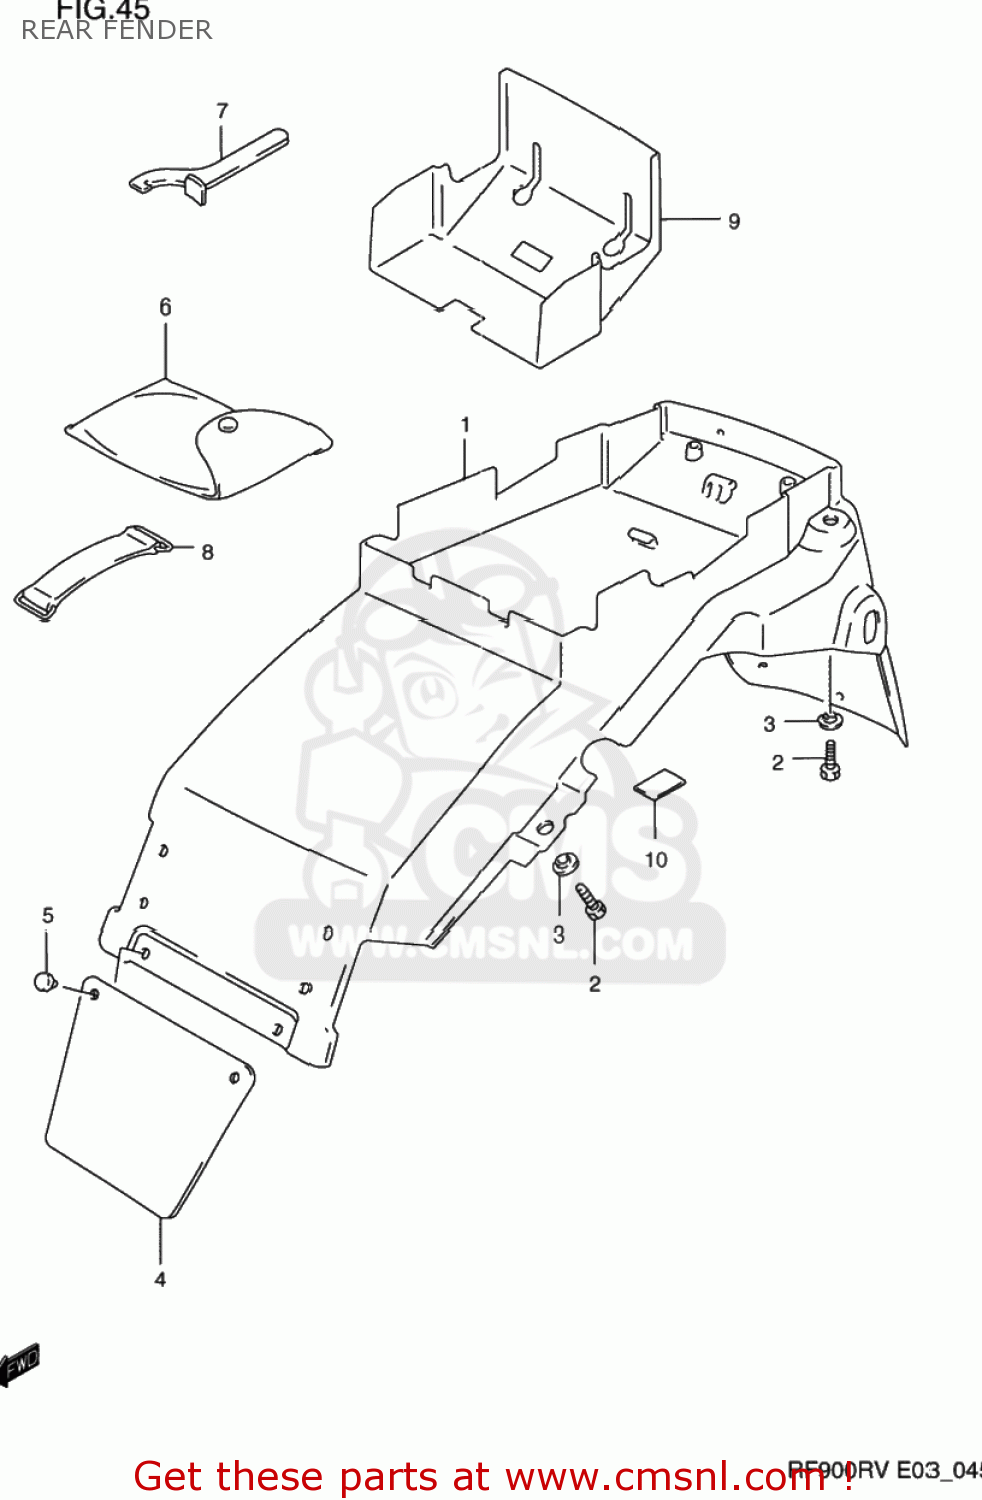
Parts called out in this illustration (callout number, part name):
1	FENDER,RR
2	BOLT
3	WASHER
4	GUARD,RR FENDER MUD
5	CLIP,MUDGUARD
6	TOOL ASSY
7	CLAMP
8	BAND
9	GUARD,REAR FENDER
10	TAPE,RR FENDER
